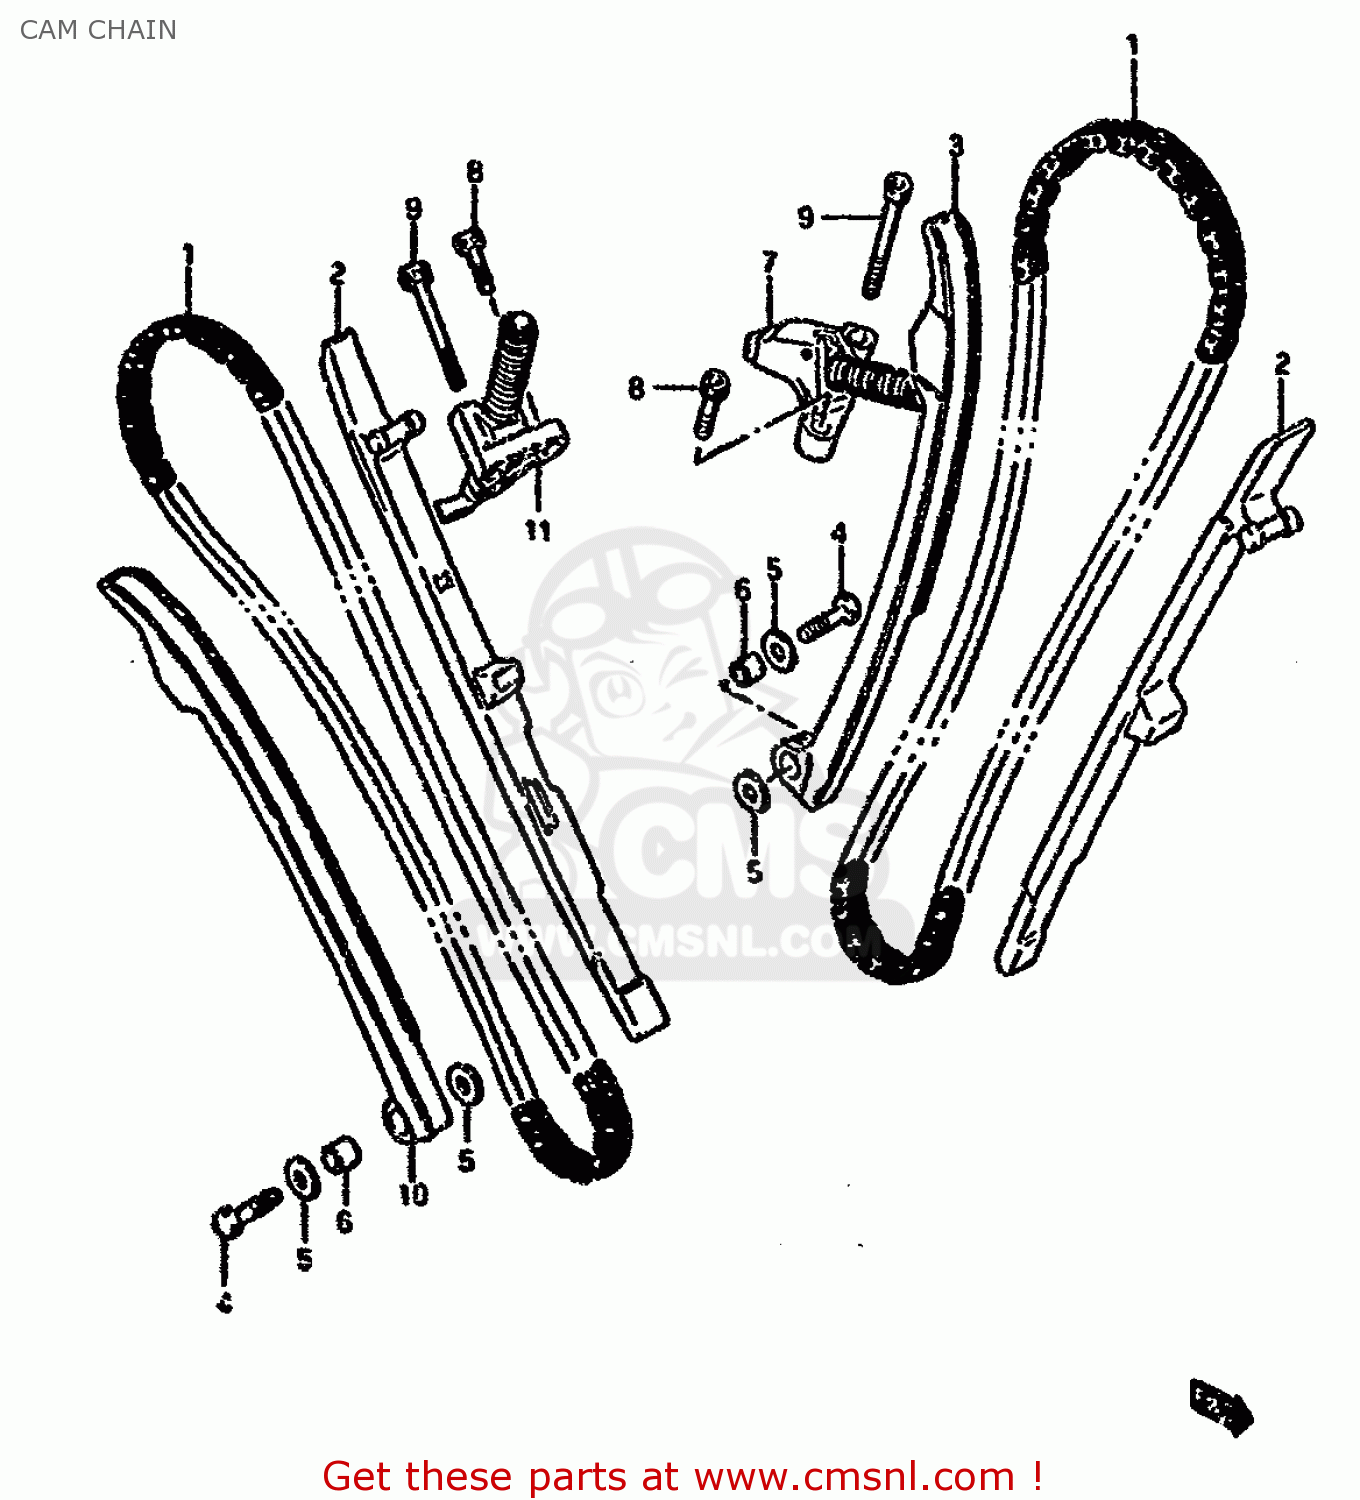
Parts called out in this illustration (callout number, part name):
1	CHAIN,CAMSHAFT DRIVE
2	GUIDE,CAM CHAIN
3	TENSIONER,FR CAM CHAIN
4	BOLT(6X26)
5	WASHER
6	SPACER(6X11X11)
7	ADJUSTER ASSEMBLY,FRONT TENSIONER
8	BOLT
9	BOLT
10	TENSIONER,RR CAM CHAIN
11	ADJUSTER ASSEMBLY,REAR TENSIONER
